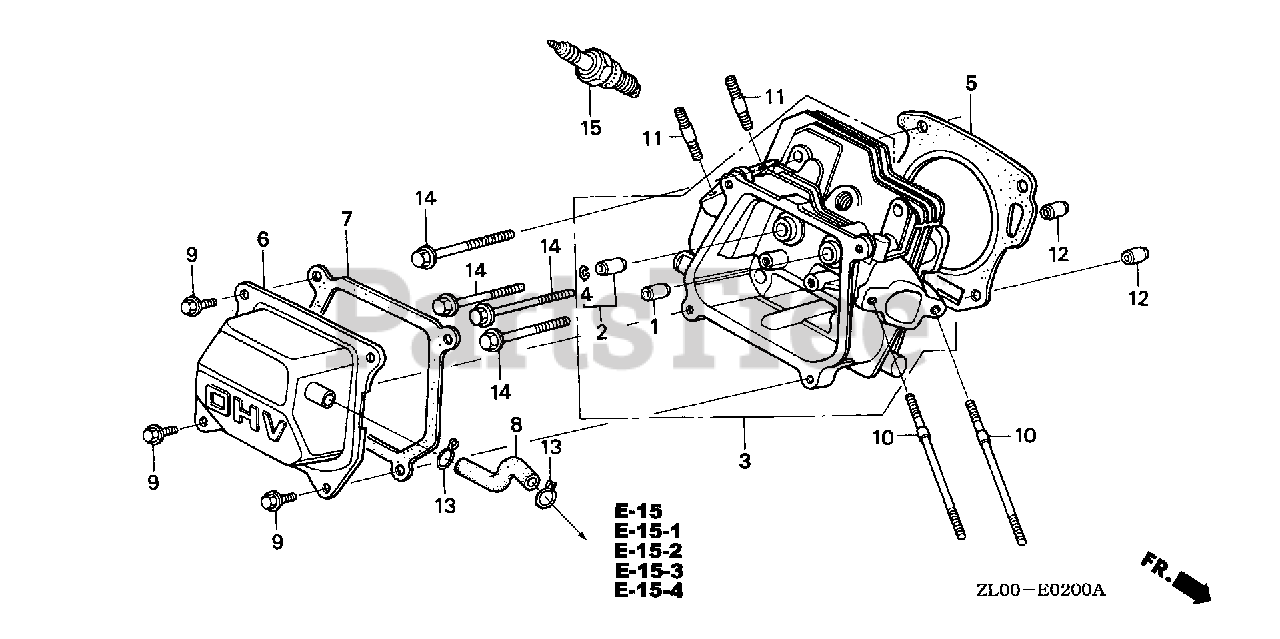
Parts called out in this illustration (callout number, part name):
1	GUIDE, VALVE (OVER SIZE)
2	GUIDE, EX. VALVE (OVER SIZE)
3	CYLINDER HEAD
4	CLIP, VALVE GUIDE
5	GASKET, CYLINDER HEAD (NIPPON LEAKLESS)
6	COVER, HEAD
7	GASKET, HEAD COVER
8	TUBE, BREATHER
9	BOLT, FLANGE (6X12) (CT200)
10	BOLT, STUD (6X112)
11	BOLT, STUD (8X32)
12	PIN, DOWEL (10X16)
14	BOLT, FLANGE (8X60)
15	SPARK PLUG (BPR5ES) (NGK)
15	SPARK PLUG (W16EPR-U) (DENSO)
15	SPARK PLUG (BPR6ES) (NGK)
15	SPARK PLUG (W20EPR-U) (DENSO)
